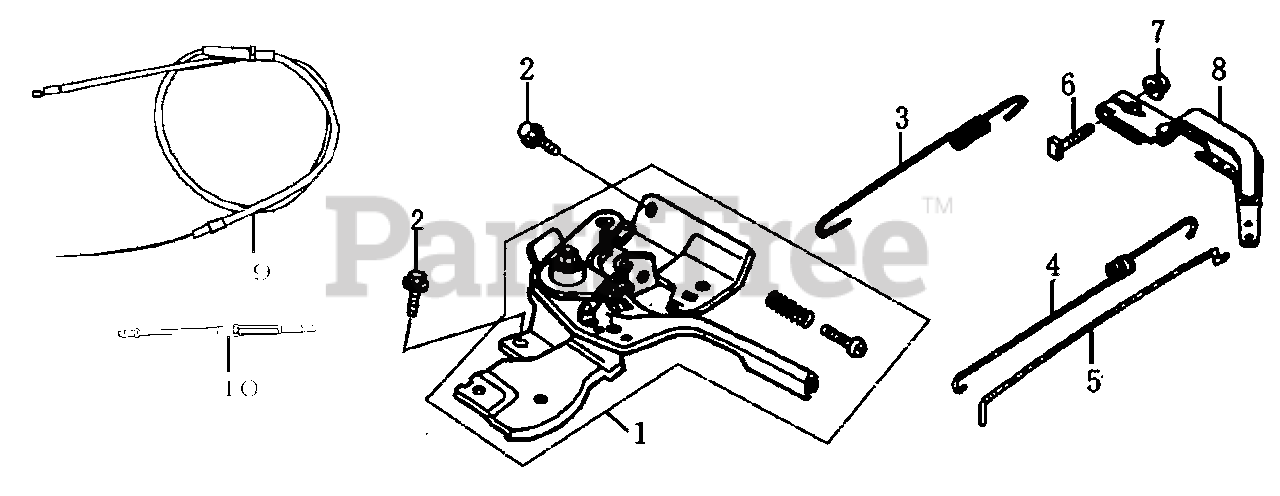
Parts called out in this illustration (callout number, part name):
1	CONTROL ASSEMBLY
2	FLANGE BOLT
3	GOVERNOR SPRING
4	THROTITLE RETURN SPRING
5	GOVERNOR GOD
6	BOLT,GOVERNOR ARM M6*21
7	FLANGE NUT
8	GOVERNOR ARM
9	CHOKE CABLE ASSEMBLY
10	DRIVE PIPE
